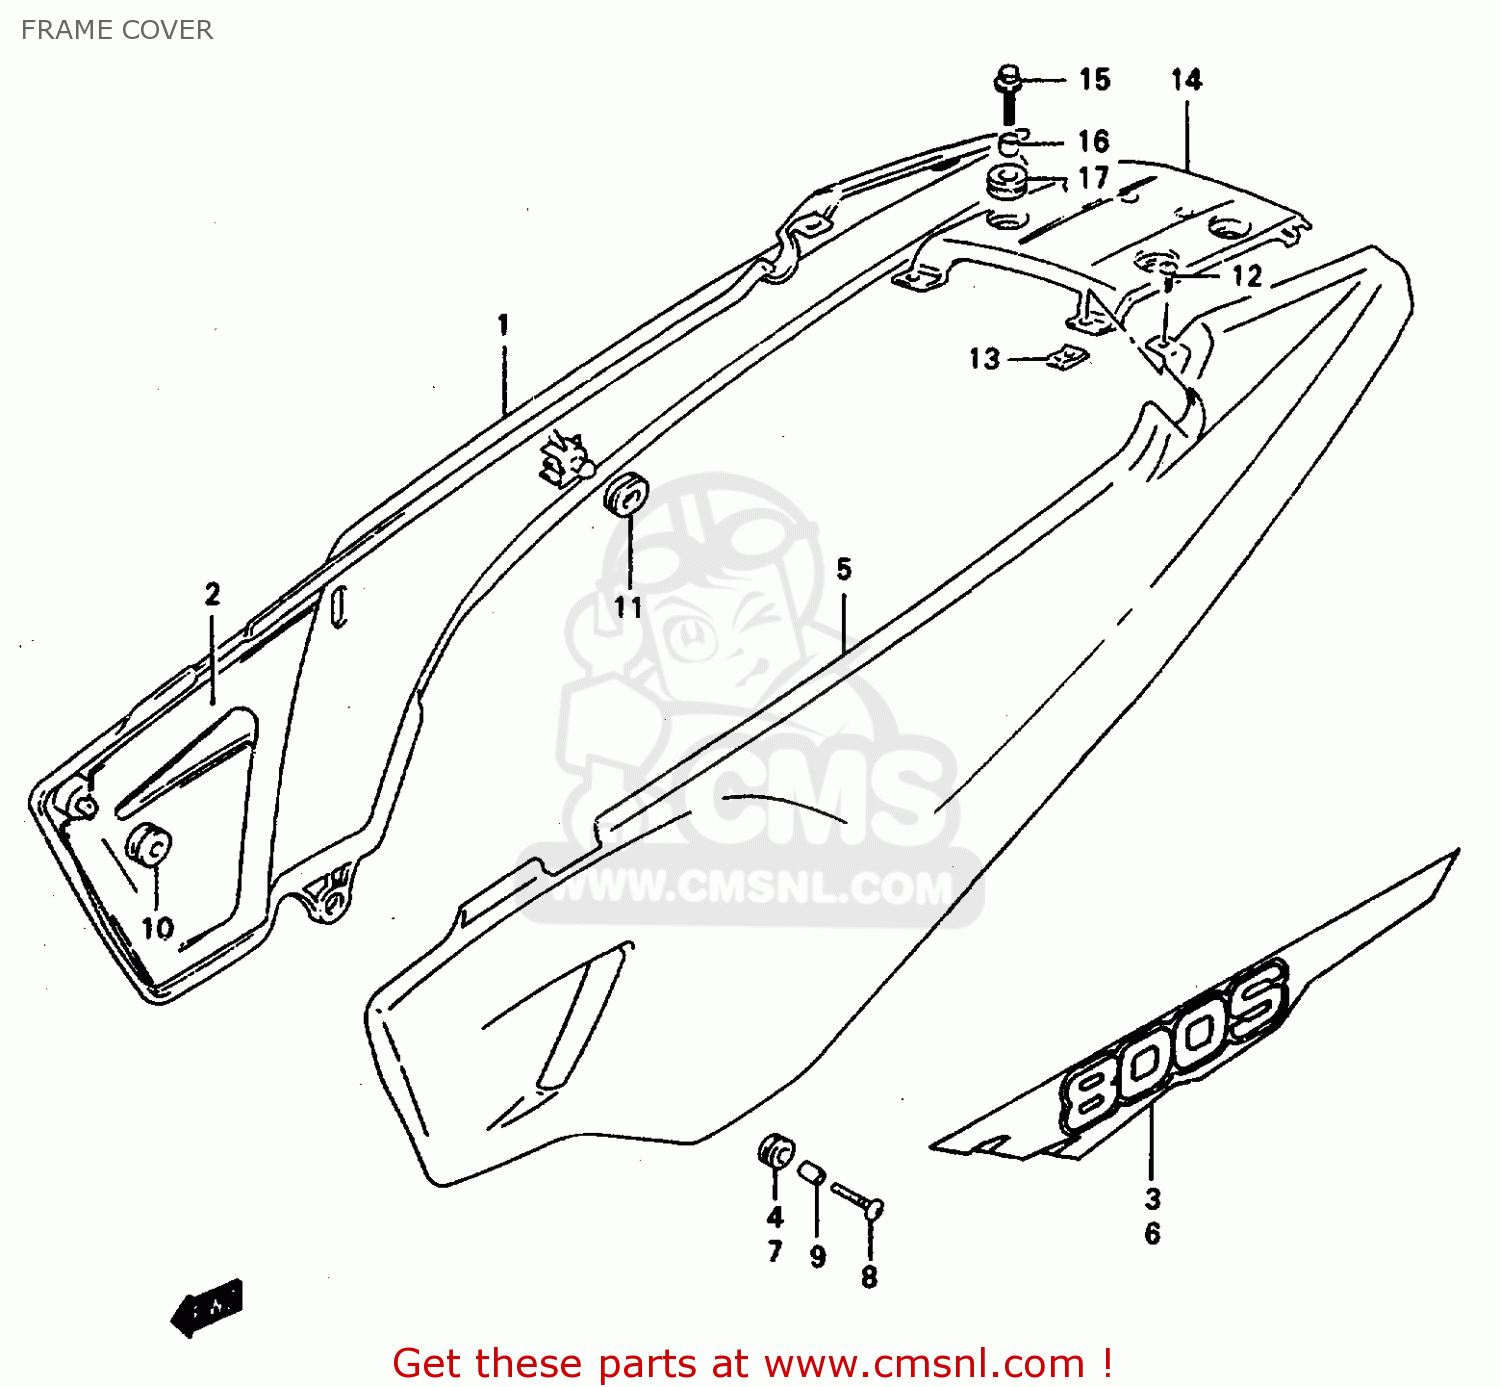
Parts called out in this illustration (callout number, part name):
1	COVER,FRAME,R(BLACK)
2	HEAT SHIELD
3	TAPE, RH
4	CUSHION
5	COVER,FRAME,L(BLACK)
6	TAPE, LH
7	CUSHION
8	SCREW(6X20)
9	SPACER(6.5X9X10)
10	CUSHION
11	CUSHION
12	SCREW L:12
13	NUT
14	COVER,FRAME CN
15	BOLT
16	SPACER(8.5X12X12.5)
17	CUSHION
